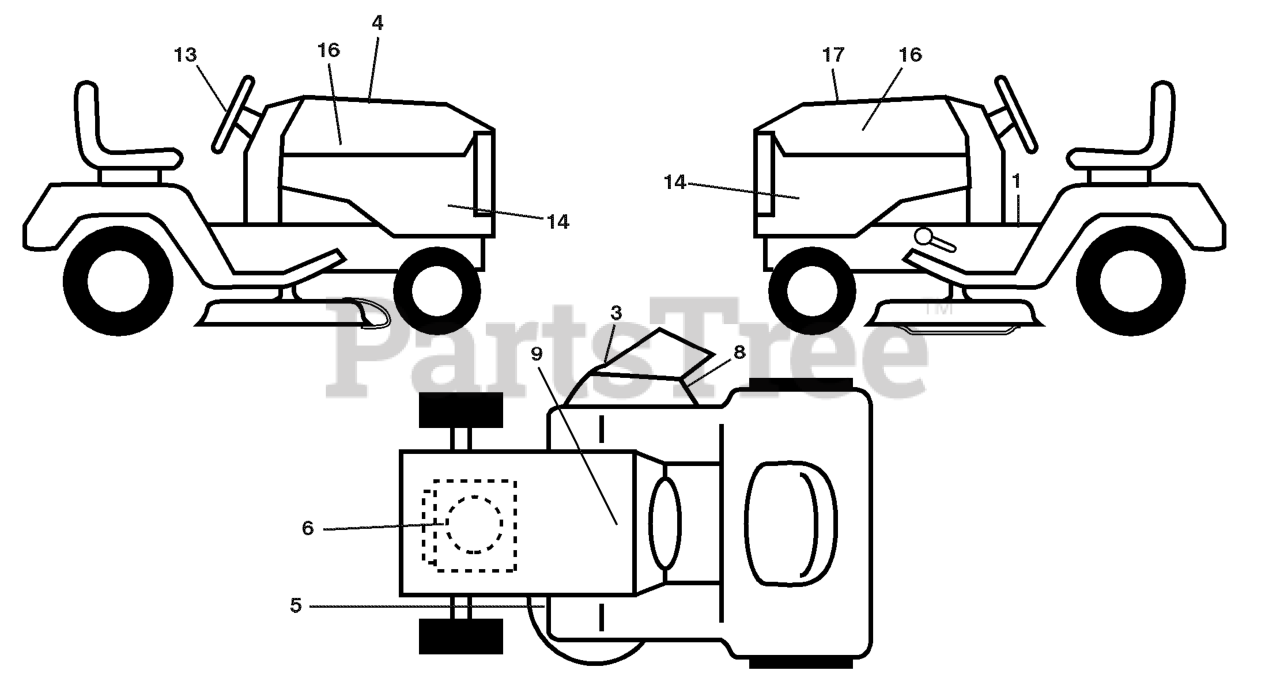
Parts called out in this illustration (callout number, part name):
1	DECAL.FENDER.WARNING.ENG
3	DECAL.WARN.KEEP.HAND.AWAY
4	DECAL HOOD CUST. RESP.
5	DECAL CLUTCH/BRAKE
6	DECAL.ENG.B&S.24HPINTK.LP.GEN
8	DECAL.MOWER.SCH.48/54
9	DECAL BTRY SYMBOLS
13	DECAL.WHEEL.STRG.LGN.H
14	DECAL PANEL
16	DECAL.HOOD.LOGO.HUSQVARNA
17	DECAL.RPL.BS.24.INTK.TGW.54.TT
17	DECAL.BYPASS.FENDER.CRD.LT.YT
17	PAD.FOOTREST.LH.HUSQ.T
17	PAD.FTRST.RH.PCH.HUSQ.
17	Manual, Owner's
